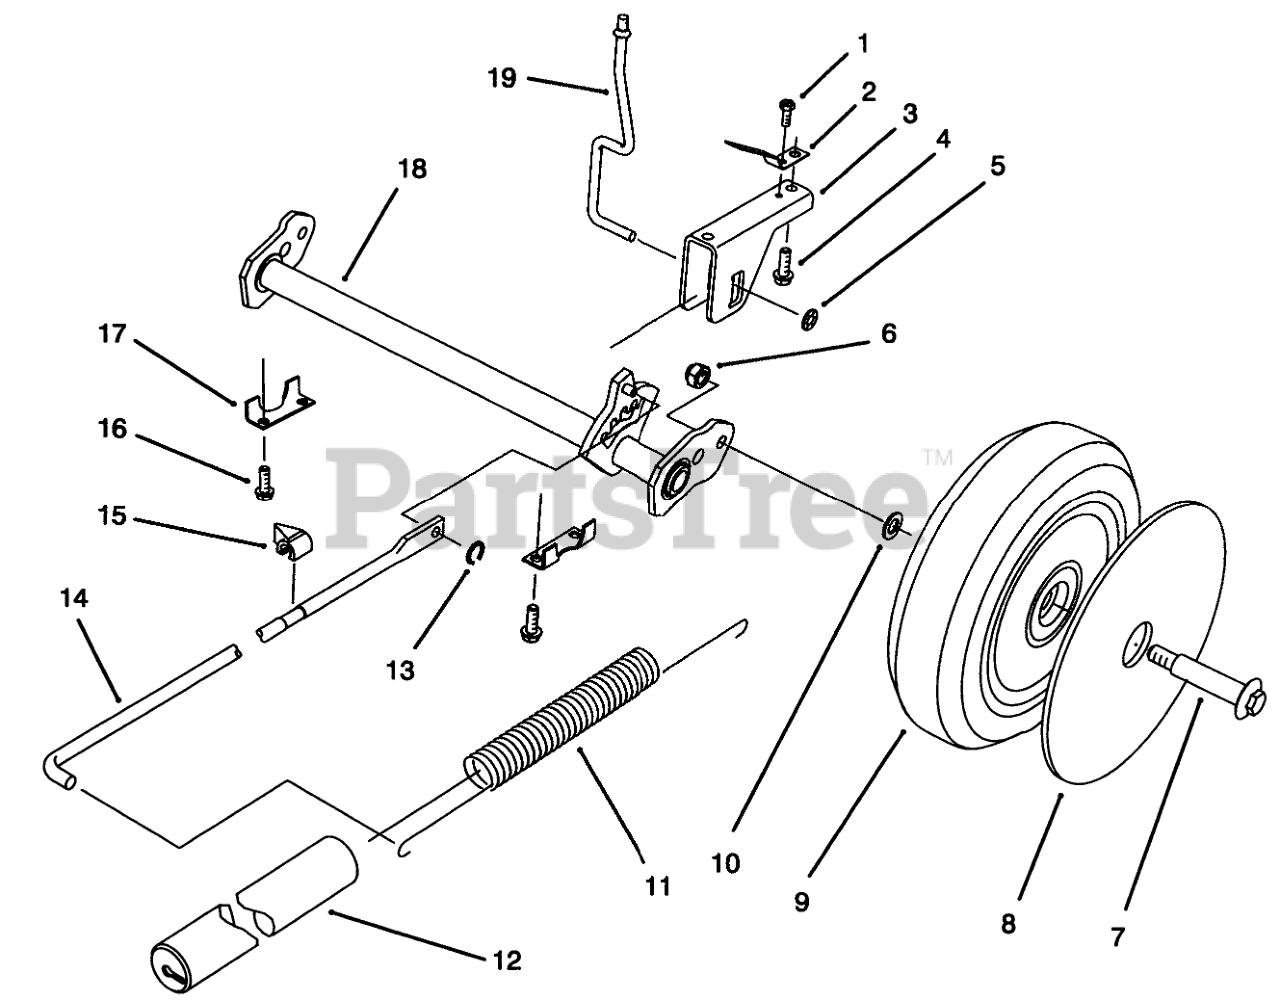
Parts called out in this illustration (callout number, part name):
1	SCREW 8 - 32 X 250
2	SPRING - TRIGGER RET
3	SADDLE - HOC
4	SCREW
5	PUSHNUT
6	NUT-HEX
7	BOLT-WHEEL
8	COVER-WHEEL
9	Wheel-ASM
10	WASHER
11	SPRING-COUNTERBALANCE
12	COVER-SPRING
13	GRIP RING
14	LINK ROD
15	INDICATOR-HEIGHT OF CUT
16	SCREW-HWH
17	REAR SECURING PLATE
18	PIVOT ARM REAR WA
19	TRIGGER ROD
